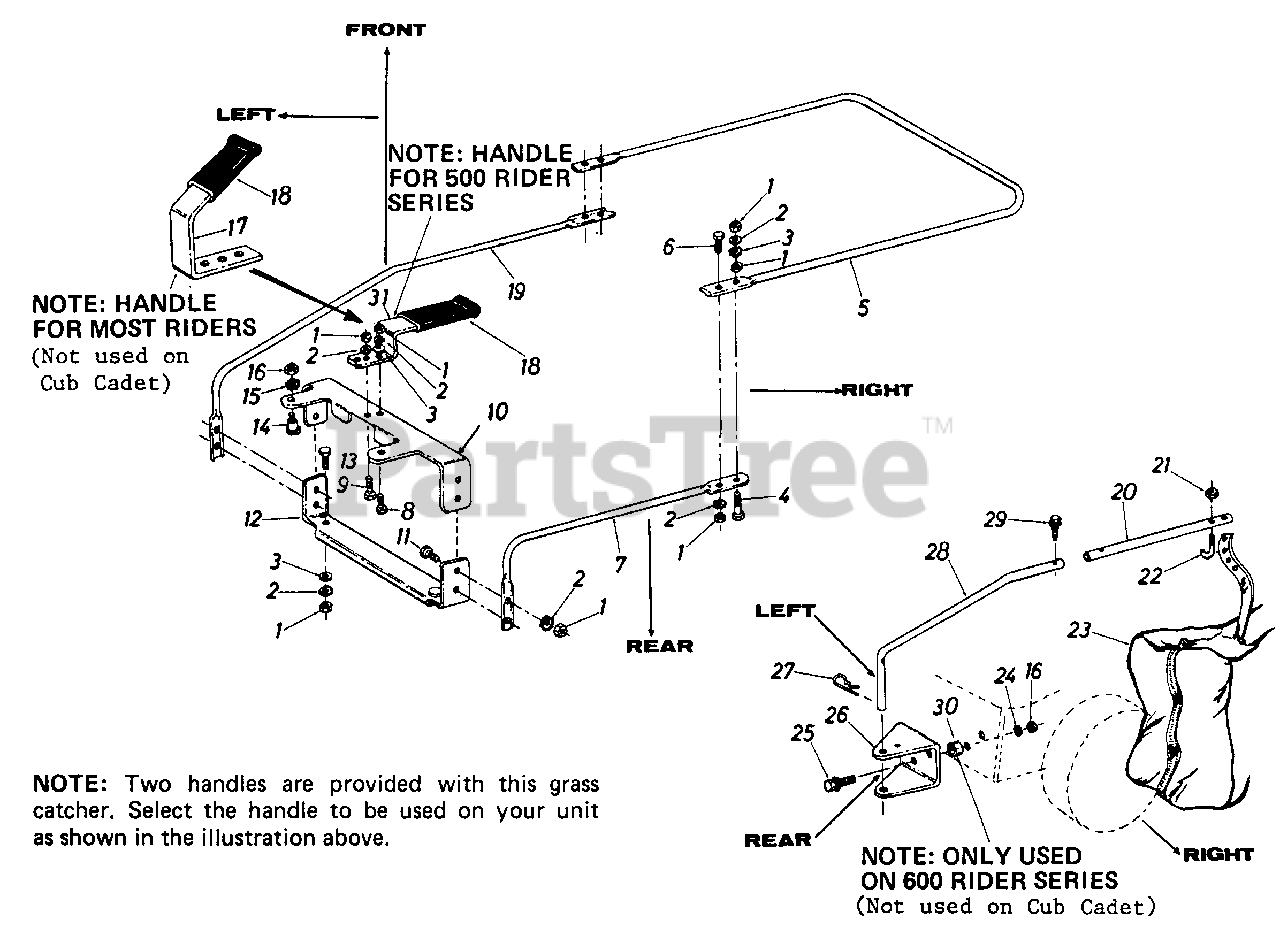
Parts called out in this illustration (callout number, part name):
1	NUT-HEX 1/4-20
2	WASHER-EXTERN L 1/4
3	WASHER-FL-.281 ID X .50 OD X .063
4	SCREW-HEX 1/4-20 X 1.50
5	FRAME-UPPER
6	SCREW-HEX 1/4-20 X 1.00
7	TUBING-FRAME-LWR
8	SCREW-HEX 1/4-20 C .62
9	SCREW-HEX 1/4-20 X .75
10	SUPPORT-UPPER
11	SCREW-HEX 1/4-20 X 1.00
12	SUPPORT-LOWER
13	SCREW-HEX 1/4-20 X .50
14	SCREW-SHLD .437 DIA X .350
15	WASHER-EXTERN L 5/16
16	NUT-HEX 5/16-18
17	BRACKET-HANDLE
18	GRIP-FL BAR-END
19	ARM-FRAME-LWR
22	HOOK-CHAIN
23	BAG-GRASS-MTD RIDER
24	WASHER-LOCK-5/16
25	SCREW-HEX SEMS 5/16-18 X .75
26	BRACKET-HITCH
27	PIN-INTERN COT-5/8 DIA
28	ARM-HOLDING-LWR
29	SCREW-HEX WASH SF TAPP
30	SPACER
31	HANDLE-CATCHER
